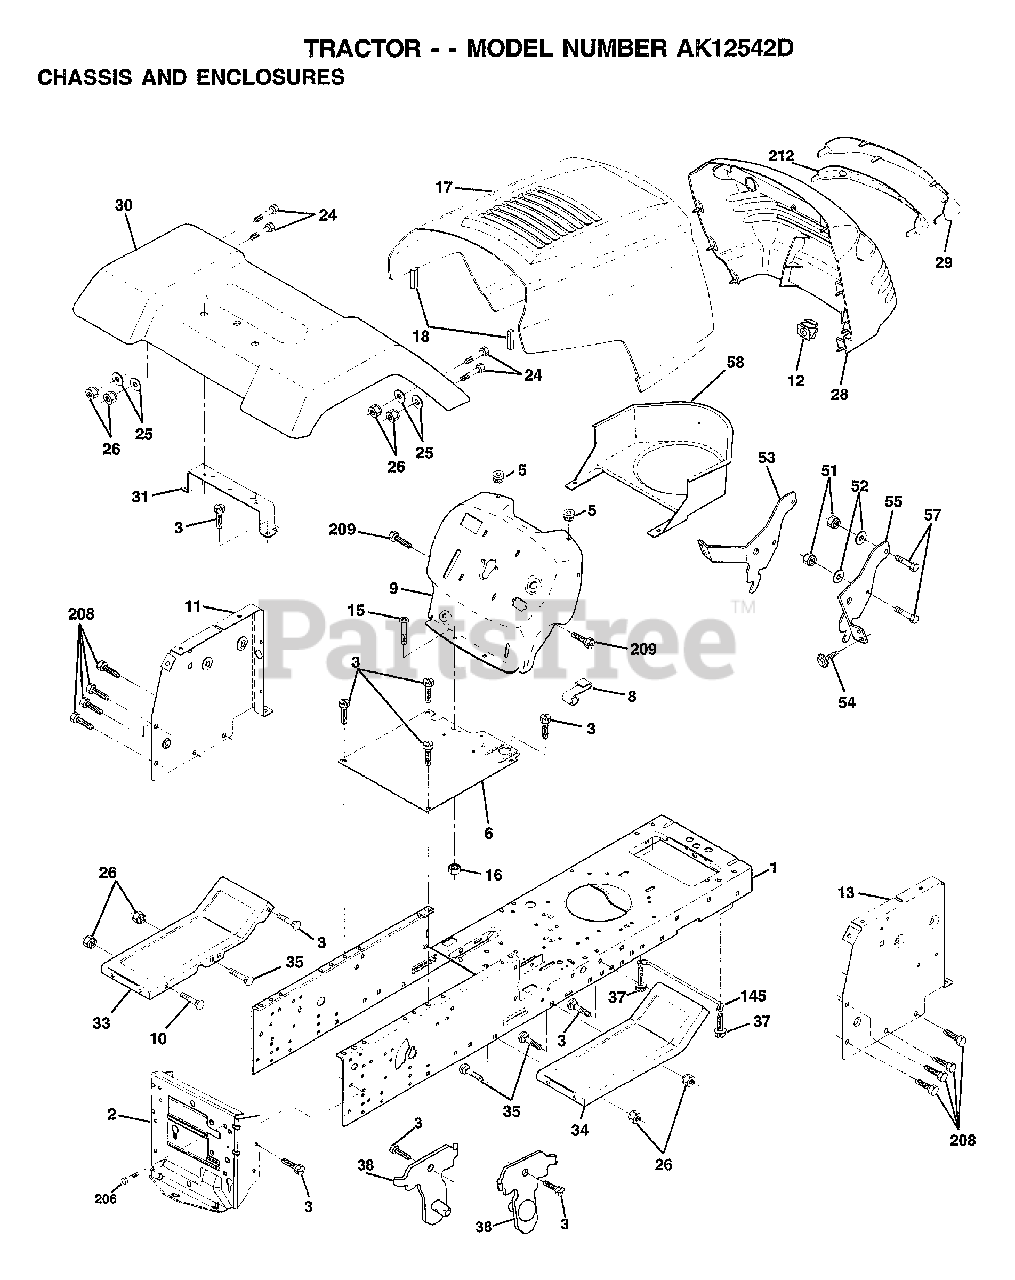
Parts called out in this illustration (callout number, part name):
2	DRAWBAR
3	SCREW
5	BUMPER-HOOD/DASH
6	SADDLE
8	CLIP.RETAINER
9	DASH
11	"PANEL-DASH,LH"
12	CLIP.TINNERMAN
15	SCREW
17	HOOD.STEEL.ASSY
24	BOLT
25	WASHER
26	NUT
28	GRILL.BLK
29	LENS.GRILLE.PRIVATE LABEL
31	BRKT FENDER
33	FOOTREST LH
34	FOOTREST RH
35	BOLT
37	SCREW LT
38	BRKT ASM PIVOT MOWER REAR
51	NUT
52	WASHER
53	BRACKET.GRILLE.LH
54	SCREW.HEX.WS.HD
55	BRACKET.GRILLE.RH
58	AIR DUCT
145	"ROD POVOT,CHASSIS"
206	BOLT SHOULDER
208	SCREW
209	SCREW
212	INSERT LENS REFLECT
